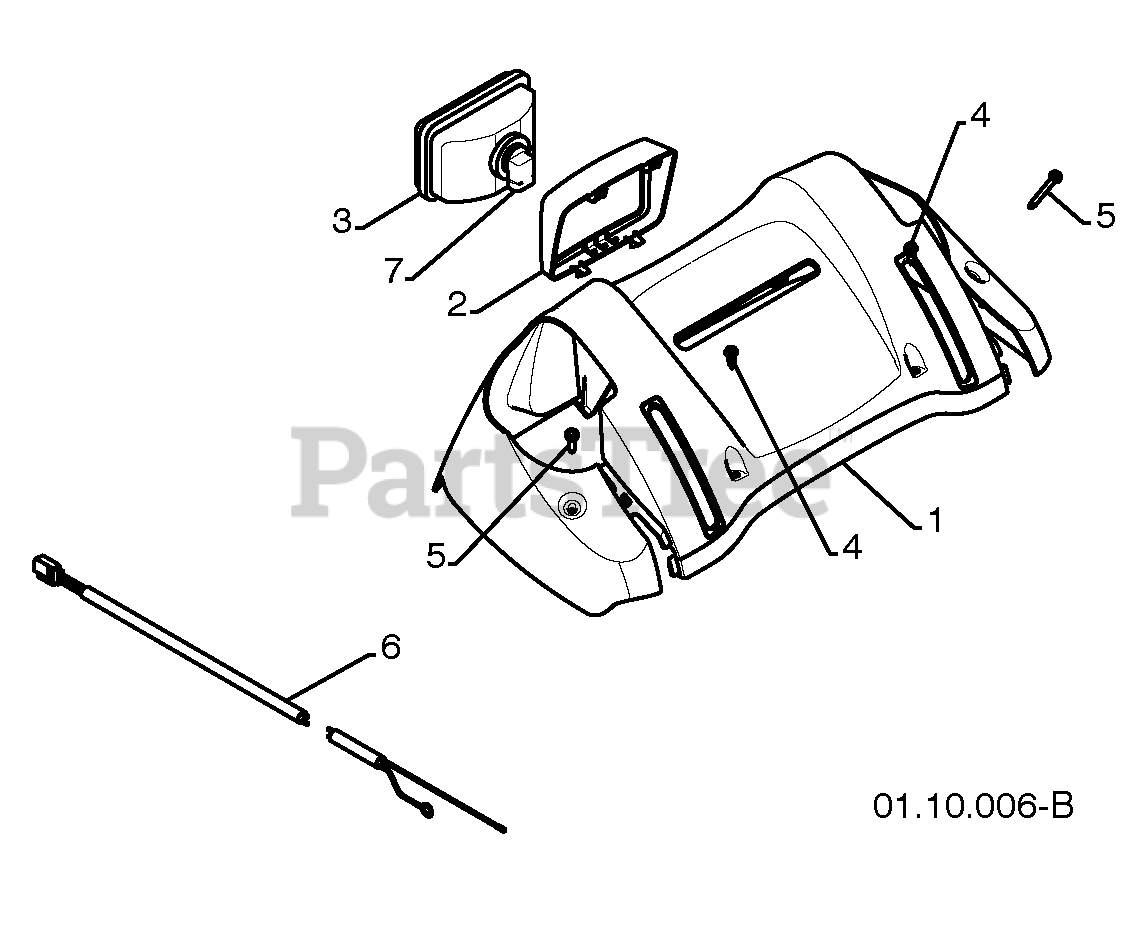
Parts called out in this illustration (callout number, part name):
1	PANEL CONSOLE
2	HEADLIGHT BEZEL
3	HALOGEN HEADLIGHT
4	SHOULDER SCREW
5	SCREW 10-24 X 1.25
6	WIRE HARNESS
7	BULB
